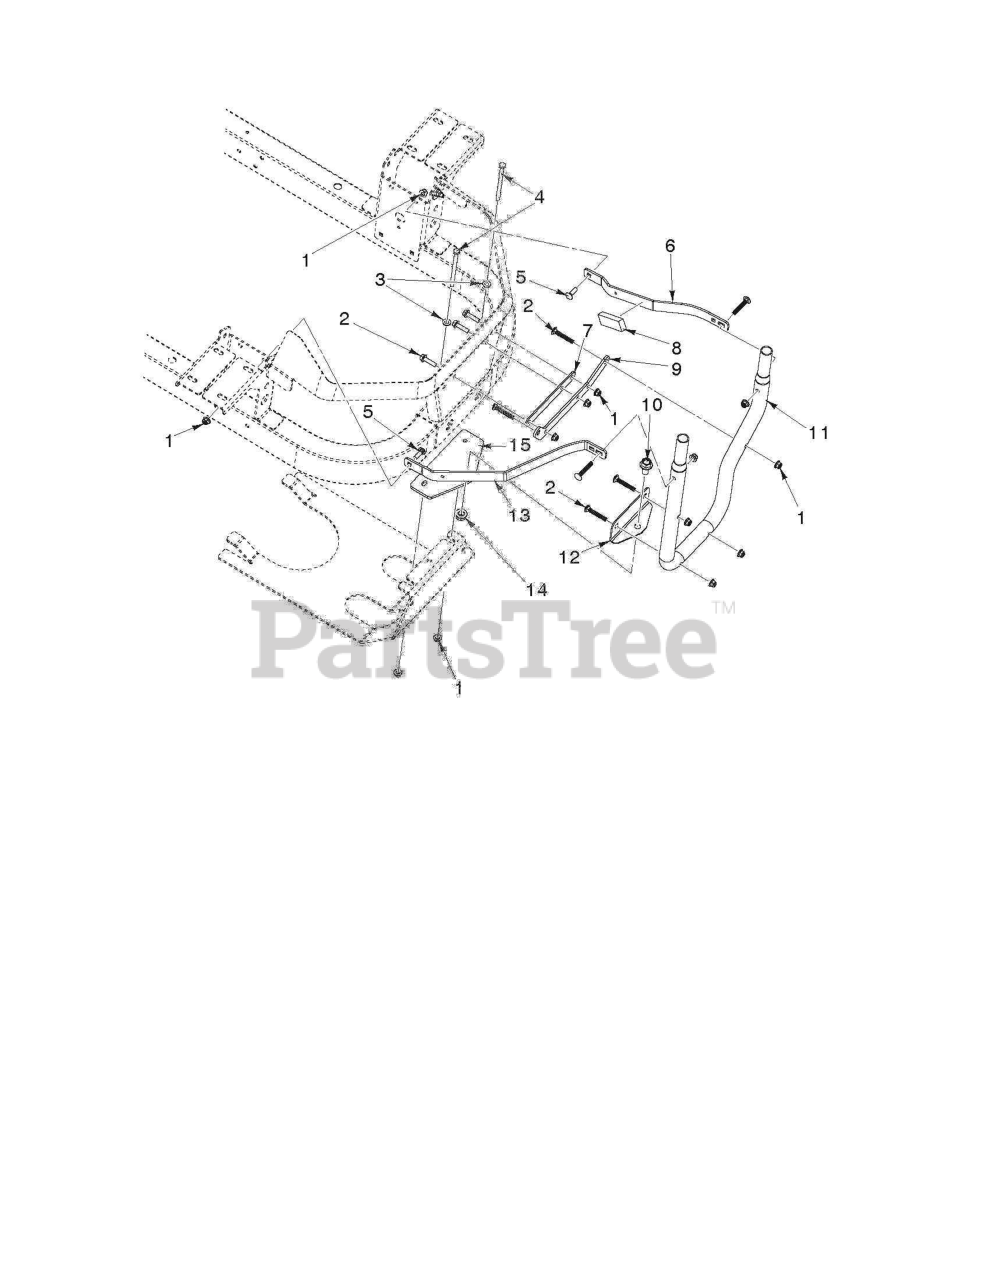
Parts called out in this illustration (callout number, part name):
1	NUT HEXAGON FLANGE 5/16-18 ST
2	Hardware
3	WASHER 11/32 X 11/16 X 14 GA T
4	BOLT 5/16-18X4 1/2
5	Bolts
6	Strap
7	SPACER, PLATE, BLK
8	FOAM STRIP, FUEL TANK
9	FOAM STRIP, FUEL TANK
10	FOAM STRIP, FUEL TANK
11	MOUNT.TUBE.COLLECTIONS
12	MOUNT, HITCH, LOWER
13	Strap
14	NUT 1/2-13 HEX FLANGE NYLOK CL
15	Brackets
